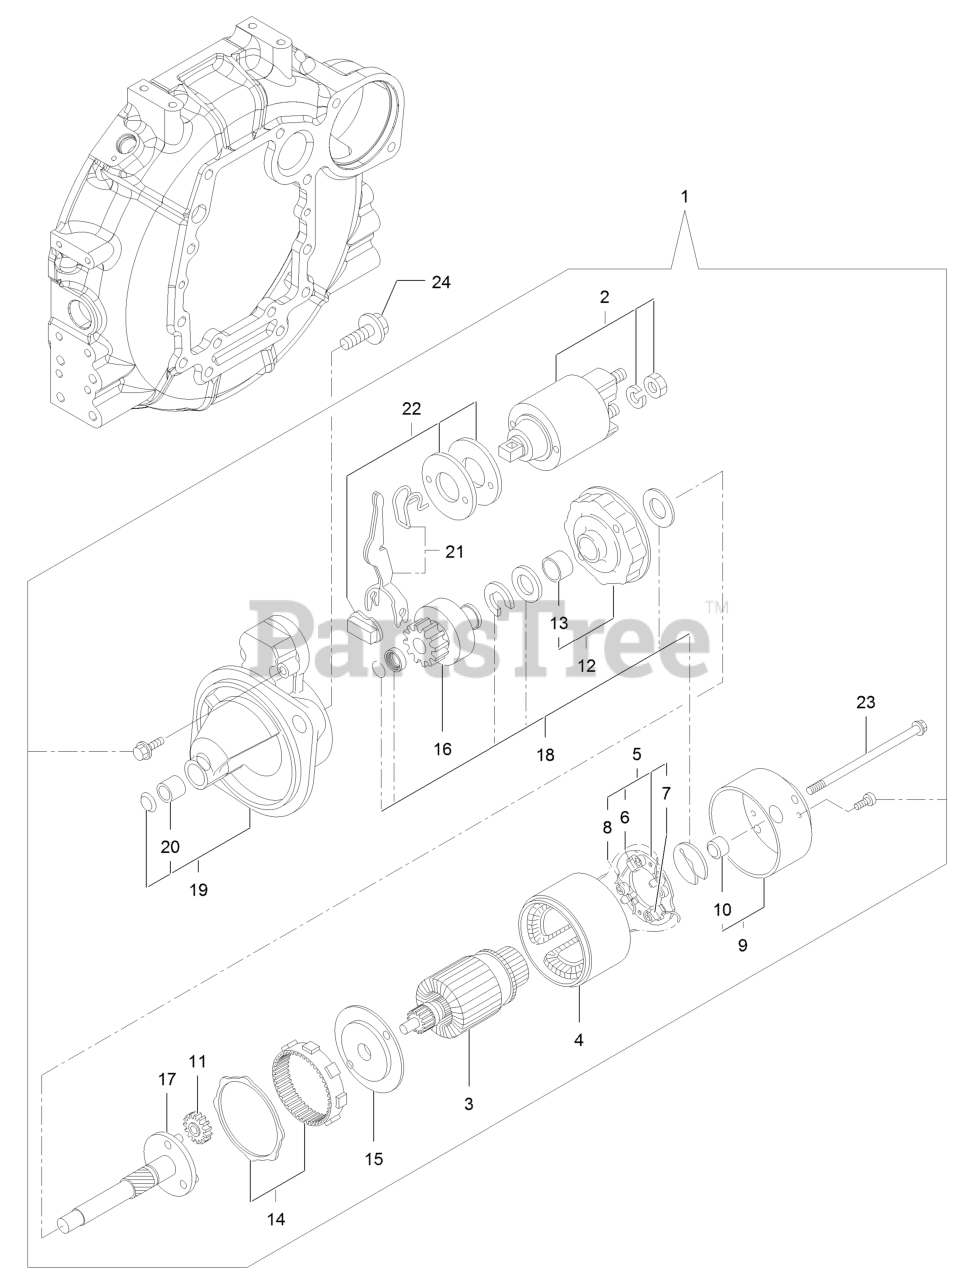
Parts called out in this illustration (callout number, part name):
1	Starter ASM
2	Switch ASM
3	Armature ASM
4	Yoke ASM
5	Brush Holder ASM
7	Brush Set
9	Cover ASM
12	Bracket
13	Bracket
15	Bracket
16	Pinion ASM
18	Washer Set
19	Case ASM
20	Metal-Starter
21	Lever Set
22	Dust Cover ASM
23	Bolt-Through
